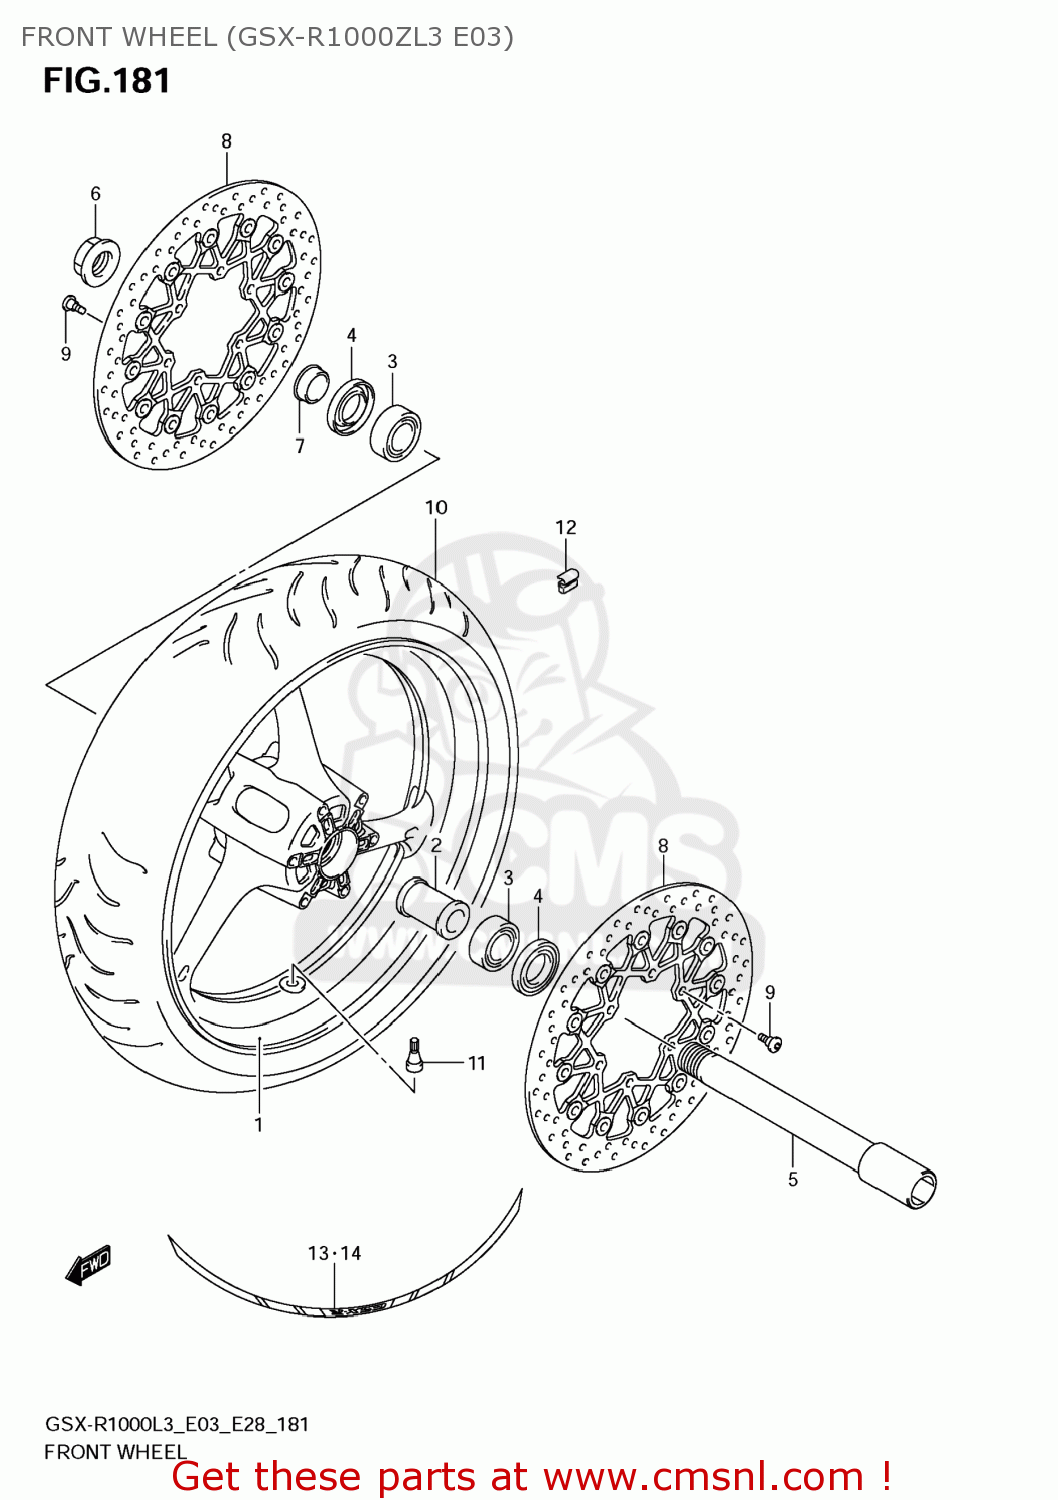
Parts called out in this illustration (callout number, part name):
1	WHEEL,FR(17M/CXMT3.50)
2	SPACER,FR HUB BEARING
3	BEARING(25X52X15)
4	SEAL,OIL(32X52X7)
5	AXLE,FR
6	NUT,FR AXLE
7	SPACER,FRONT A
8	DISC,FR BRAKE
9	BOLT(6X21)
10	TIRE,FR
11	VALVE ASSY,WHEEL RIM(TR412)
12	BALANCER,WHEEL(10G)
13	TAPE,WHEEL FR
14	TAPE,WHEEL FR
